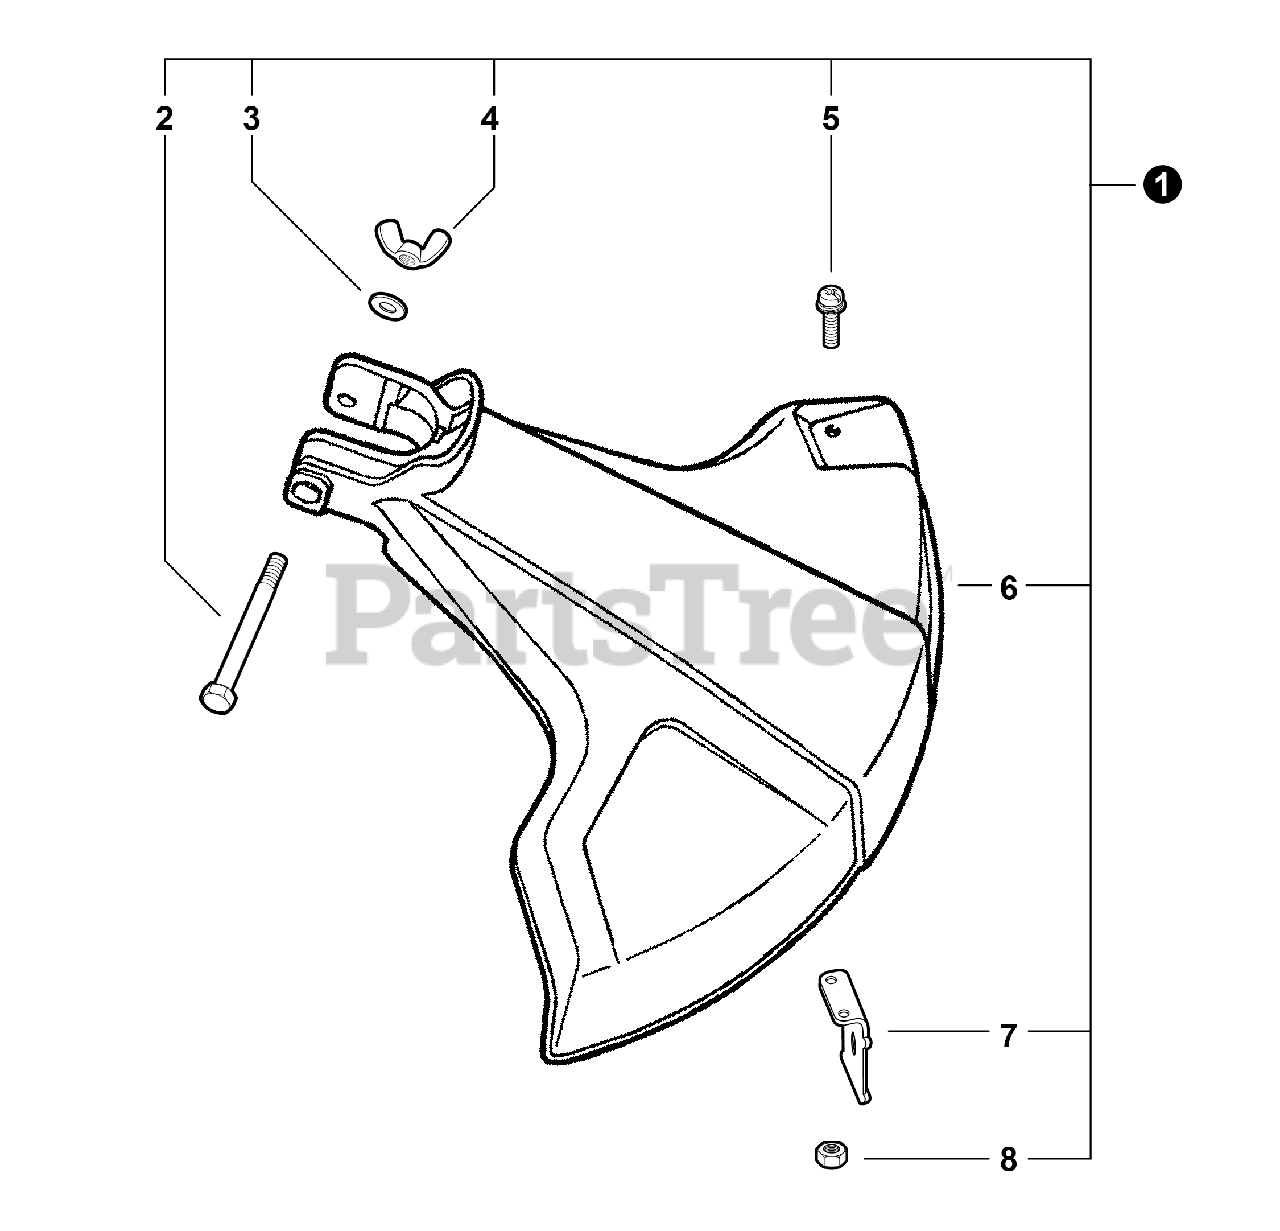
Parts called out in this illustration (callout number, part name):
1	SHIELD ASY
2	BOLT - 1/4-20 X 2"
3	WASHER - 1/4"
4	WINGNUT - 1/4-20
5	SCREW - 5X12 -- TORX
6	SHIELD, DEBRIS - PLASTIC
7	KNIFE, TRIMMER LINE
